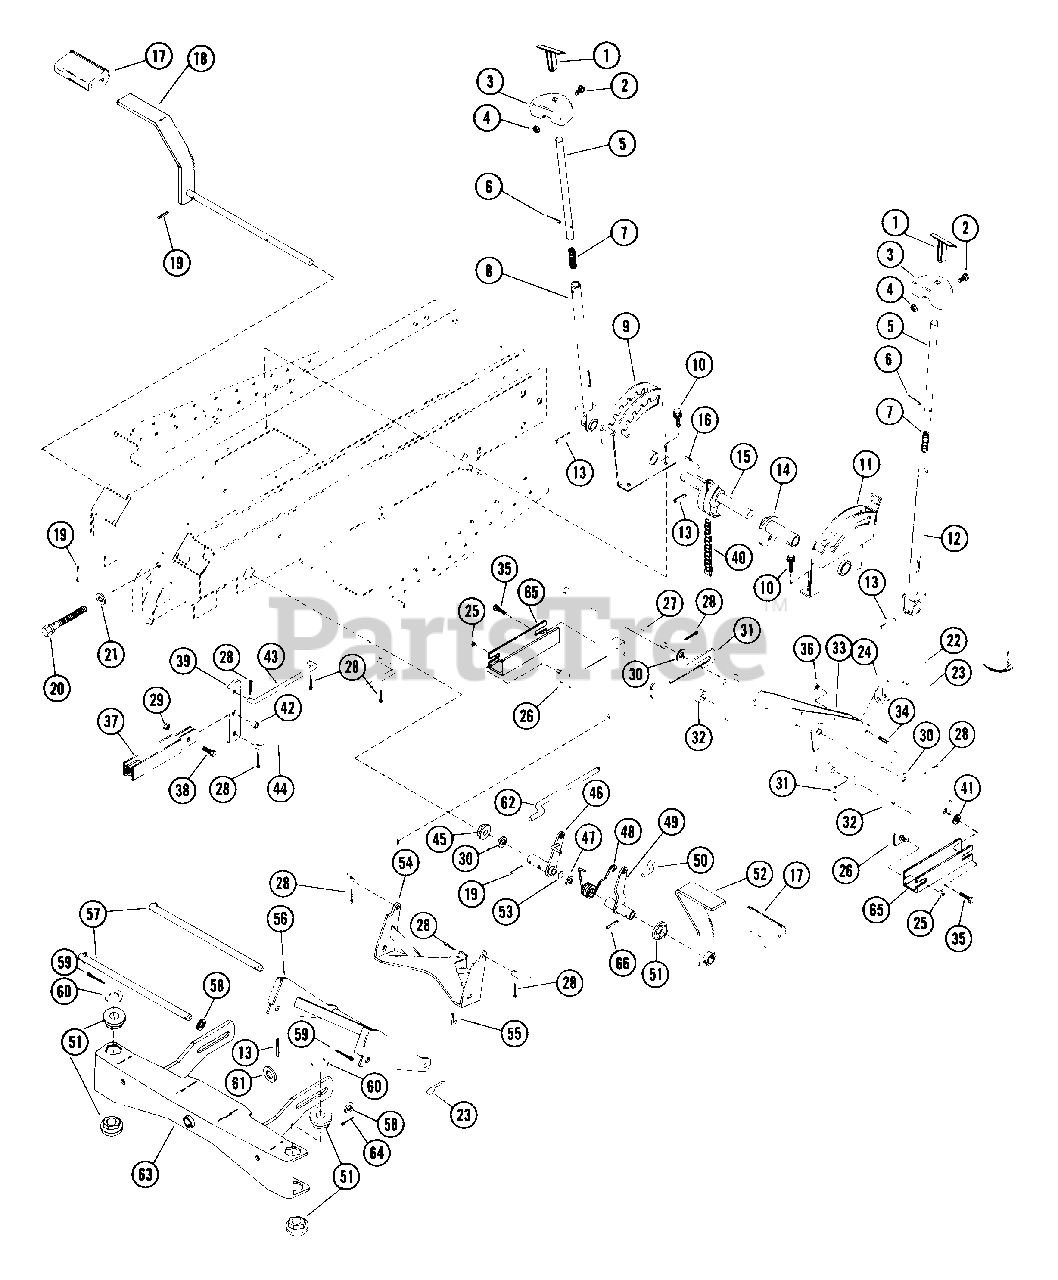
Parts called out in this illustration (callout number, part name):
1	T PLUNGER
2	BLT-HEX 10-24X1.25 FHPL
3	T HANDLE
4	NUT-LK TOP 10-24 PL
6	PIN-ROLL .188X1.50
7	SG-COMP ??X.44X?? WLD 10
8	PAN RAISING HANDLE
9	ATTACHMENT LIFT QUADRANT
10	BLT-SERHFWH .31-18X.50 PL
11	ENGAGEMENT QUADRANT
12	ENGAGEMENT HANDLE
13	PIN-ROLL .250X1.25
14	ENGAGEMENT LEVER
15	MOWER LIFT DRUM
16	PIN-ROLL .156X.88
17	PEDAL COVER
18	BRAKE PEDAL
19	PIN-ROLL .188X1.00
20	CAP SCREW
21	WSHR-FL-STL .505X1.000X.062
22	CLEVIS PIN
23	PIN-HAIR INT .08X.38X1.42 YWZC
24	SWIVEL BLOCK
25	NUT-FLG. .312-18 PL
26	PAN RAIL
27	FLOAT PIN
28	PIN-COTR .12X1.0 PL
29	NUT-LK .312-18 GR A PL
30	WSHR-FL-STL .531X1.062X.095 PL
31	REAR LIFT LINK
33	REAR MOWER HANGER
34	BLT-HEX .38-16X1.75 PL GR2
35	BLT-SERHFWH .31-18X.75 PL
36	NUT-LK-CTR .375-16 GR A PL
37	ADJUSTMENT YOKE
38	BLT-HEX .31-18X.88 PL GR2
39	PIVOT LINK
40	ROLLER CHAIN
41	WSHR-FL-STL .38X.875X.083 PL
42	SPACER BUSHING .5 X .32 X .21
44	MOWER ENGAGEMENT LINK
45	FLANGE BUSHING
46	BRAKE ARM
47	WAVE WASHER .531X.781X.125FH
48	SG-TORS .088X.75X3.0
49	CLUTCH ARM
50	CLUTCH ROD
51	FLANGE BUSHING
52	CLUTCH PEDAL
53	WSHR-FL-STL .505X.875X.024 PL
56	MOWER LIFT ARM
57	HANGER PIN
58	WSHR-FL-STL .505X.880X.072 PL
59	PIN-COTR .12 X 1.25 PL
60	WSHR-FL-STL .755X1.375X.062 PL
61	WSHR-FL-STL .755X1.375X.125 PL
62	BRAKE ROD
63	AXLE
64	PIN-COTR .09X1.0 PL
65	CHANNEL
66	PIN-ROLL .188X1.25
